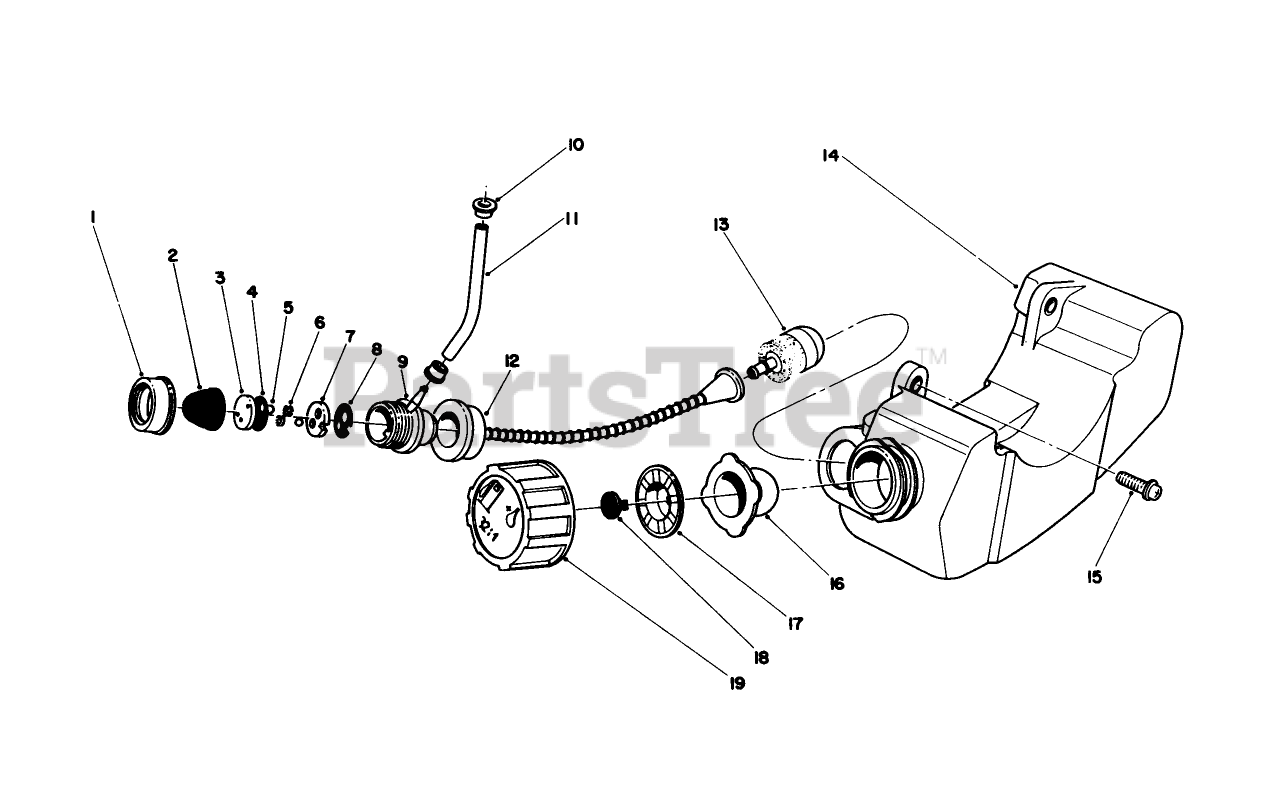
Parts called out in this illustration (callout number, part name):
1	PUMP CAP
3	SEAT VALVE
4	GASKET
6	SPONGE
7	SEAT VALVE
8	GASKET
9	Pump-Primer (Incl. Ref. #1-8)
11	FUEL TUBE
12	SUCTION HOSE
13	FUEL FILTER
14	Fuel Tank Assembly (Incl. Ref. #1-9, 12, 13, 16-19)
15	Screw
16	GASKET - PACKING
17	HOLDER
18	BREATHER VALVE
19	TANK CAP
